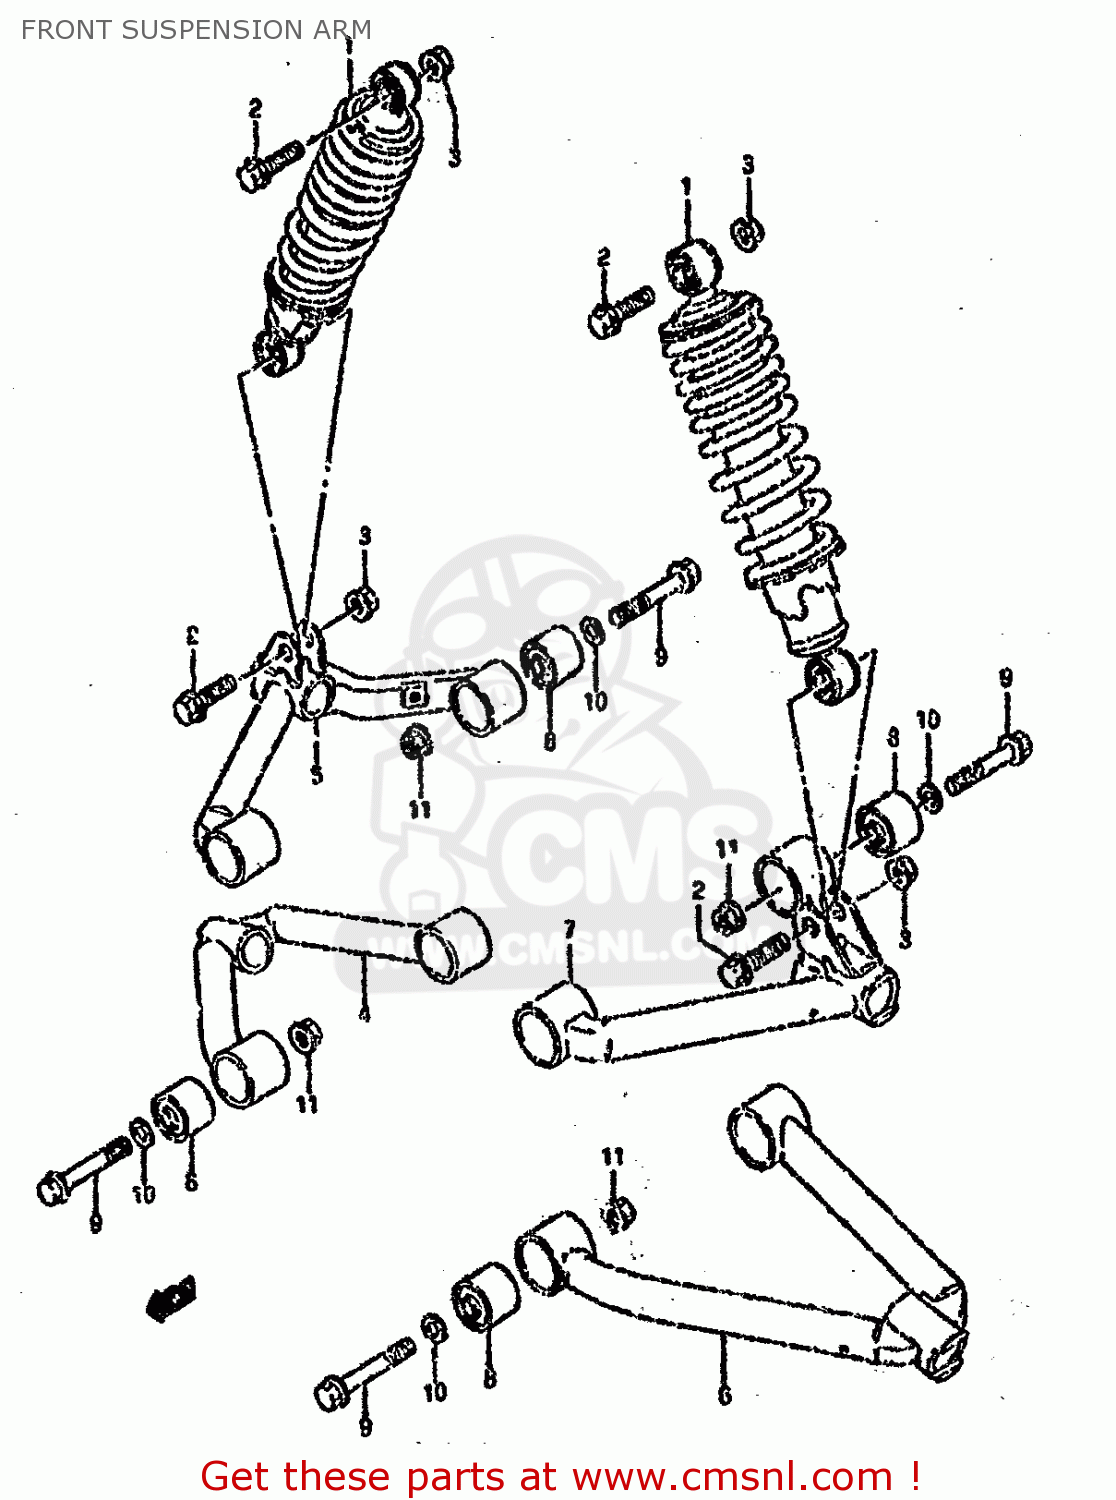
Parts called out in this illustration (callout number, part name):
1	ABSORBER ASSEMBLY,FRONT SHOCK
2	BOLT(10X37)
3	NUT
4	ARM,SUSPENSION
5	ARM COMP,SUSPENSION,UPPER
6	ARM COMP,SUSPENSION,LOWER
7	ARM COMP,SUSPENSION,UPPER
8	BUSH
9	BOLT(10X60)
10	WASHER,LOCK
11	NUT 10MM
